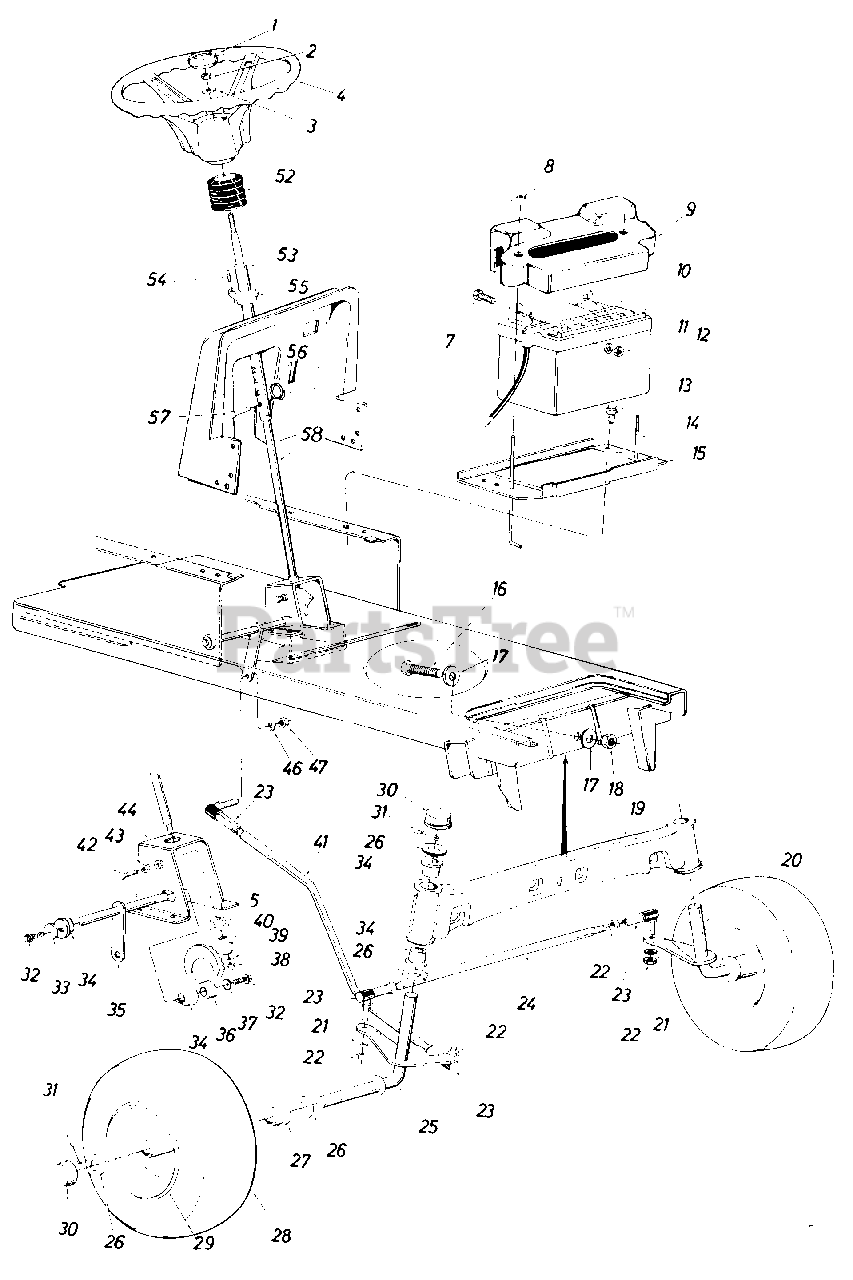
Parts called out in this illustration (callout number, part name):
1	Steering Wheel Cap
2	Hex Cent. L-Nut 5/16-18 Thd.
3	Bell-Wash. 5/16" I.D. x .87" O.D. x .060
4	Steering Wheel
7	Hex Scr. 1/4-20 x .62" Lg.
8	Wing Nut Plastic 1/4-20 Thd.
9	Battery Cover
10	12-V Battery
11	L-Wash. 1/4" I.D.
12	Hex Nut 1/4-20 Thd.
13	Hex Thd. Rolling Scr. 1/4-20 x.50" Lg.
14	Battery Hold Down Rod
15	Battery Plate
16	Hex Scr. 5/8-18 x 2.50" Lg.
17	Flat Wash. .66" I.D. x 2.25" O.D. x .17
18	Hex Cent. L-Nut 5/8-18 Thd.
19	Front Pivot Bar Ass'y.
20	Front Axle Ass'y. L.H.
21	L-Wash. 3/8" Scr.
22	Hex Jam Nut 3/8-24 Thd.
23	Ball Joint Ass'y.
24	Tie Rod
25	Front Axle Ass'y. R.H.
26	Fl-Wash. .780 I.D. x 1.59 O.D.
27	Flange Bearing
28	Front Wheel Ass'y. Comp.
29	Front Wheel Rim Only
30	Dust Cover
31	Cotter Pin 5/32" Dia. x 1.00" Lg.
32	Hex Scr. 3/8-24 x .75" Lg. Grade 5
33	Fl-Wash. 3/8 I.D. x 1.25 O.D. x .090
34	Flange Double "D" Brg. .753 I.D.
35	Steering Arm Shaft Ass'y.
36	Side Gear Steering
37	Bell-Wash. 3/8" I.D.
38	Hex Cent. L-Nut 5/16-24 Thd.
39	Fl-Wash. 5/16" I.D. x .62 O.D. x .059
40	Pinion Gear Steering
41	Drag Link
42	Hex Nylon Scr. 3/8-16 x 1.25"
43	Hex Nut 3/8-16 Thd.
44	Steering Gear Sup. Ass'y.
46	L-Wash. 3/8" Scr.
47	Hex Nut 3/8-24 Thd.
52	Steering Bellow
53	Upper Steering Shaft
54	Oval Hd. Cr.-Sunk Scr. #10 x 5/8" Lg.
55	Fl-Bearing .89" I.D. x 1.36" O.D.
56	Hex L-Nut 1/4-20 Thd.
57	Hex Bolt 1/4-20 X 1.31" Lg.
58	Lower Steering Shaft
